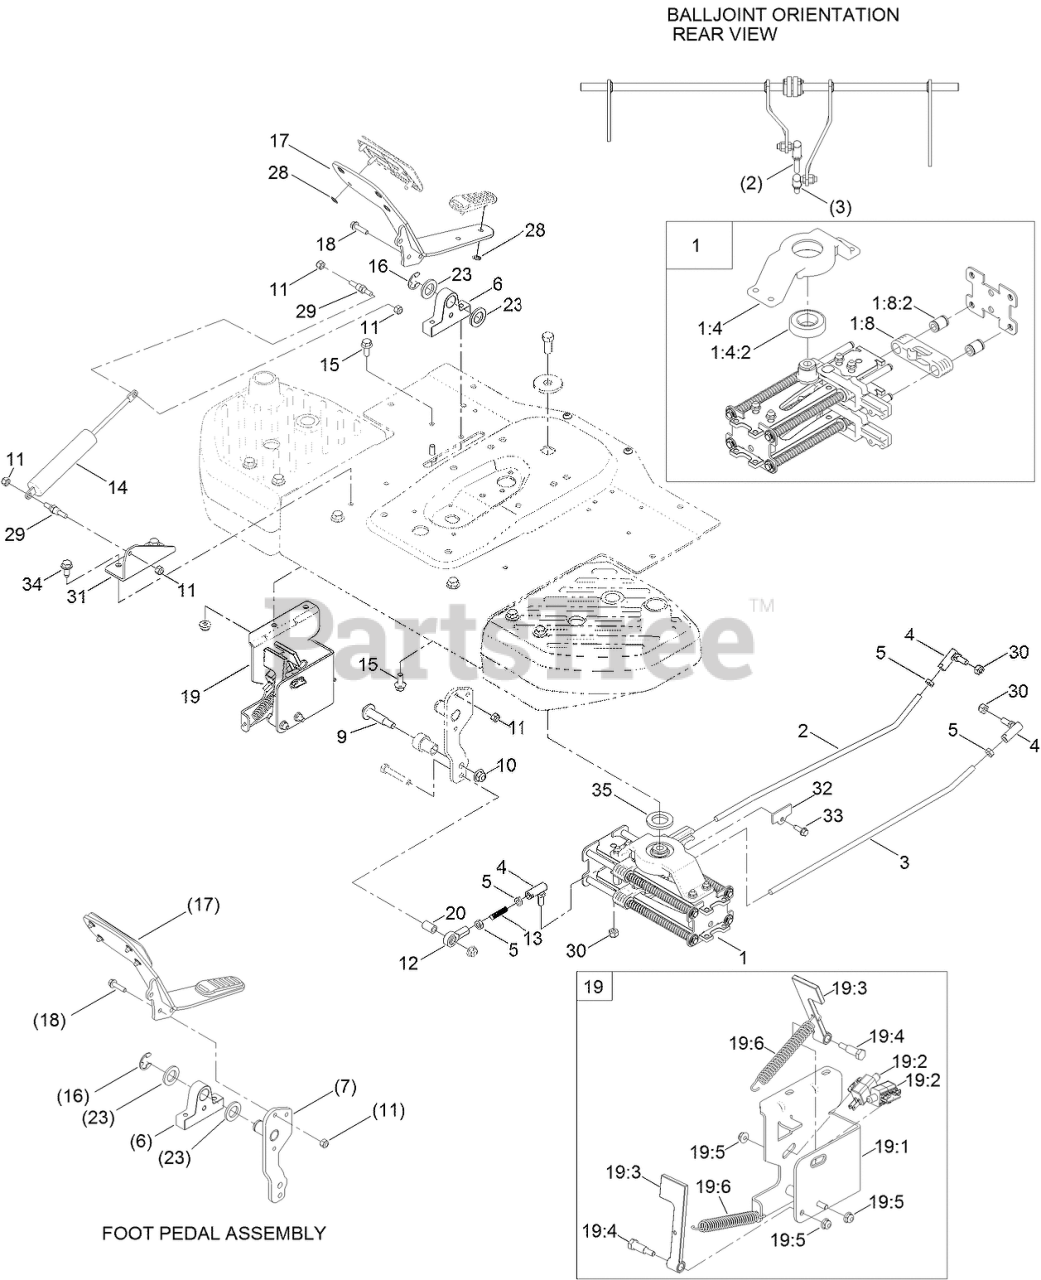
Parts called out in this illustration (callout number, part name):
1	SPEED CONTROL ASM
1:4	SPEED CONTROL BRACKET ASM (WITH BEARING)
1:4:2	BEARING-BALL
1:8	SPEED CONTROL SLIDE ASM (WITH BUSHINGS)
1:8:2	BUSHING
2	ROD-HYDRO, RH
3	ROD-HYDRO, LH
4	BALLJOINT-RH (W/GROMMET)
5	NUT-JAM
6	MOUNT-PEDAL PIVOT
9	BOLT-WHEEL
10	NUT-HF, NI
11	NUT-LOCK, NI
12	BALLJOINT-RH
13	ROD-THREADED
14	DAMPER-NON CAVITATING
15	SCREW-HHF
16	E-RING
17	PEDAL-TRACTION
18	SCREW-HHF
19	NEUTRAL RETURN ASM
19:1	BRACKET-SWITCH
19:2	SWITCH
19:3	ARM-SWITCH
19:4	BOLT-SHOULDER
19:5	NUT-HF
19:6	SPRING-EXTENSION
20	SPACER
23	WASHER
28	NUT-PUSH
29	STUD-DAMPER
30	NUT-LOCK
31	BRACKET-DAMPER
32	COVER-END ROD
33	SCREW-HWH, THREAD ROLL
34	SCREW-HWHTF
35	SPACER-BEARING
